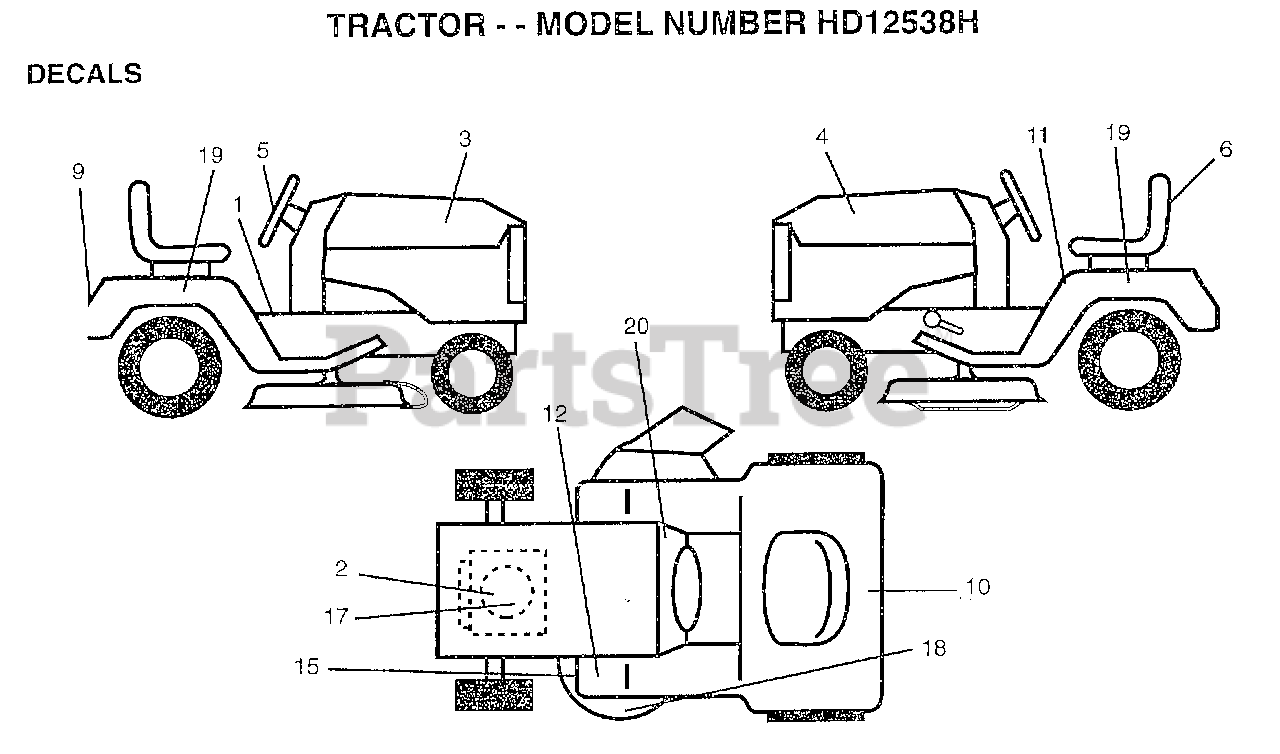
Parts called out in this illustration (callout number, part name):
3	DECAL HOOD RH
4	DECAL HOOD LH
5	DECAL, INS STRG WH
6	DECAL.SEAT REPLACEMENT
9	DECAL.FENDER.LOGO
10	DECAL.BATRY.3-3908
11	"DECAL FENDER,DANG"
12	DECAL CLUT/BRAKE
15	DECAL
17	DECAL ENGINE
18	DECAL.MOWER.HOME
19	DECAL.FEND.SD.5SP
20	"DECAL,DASH PNL"
